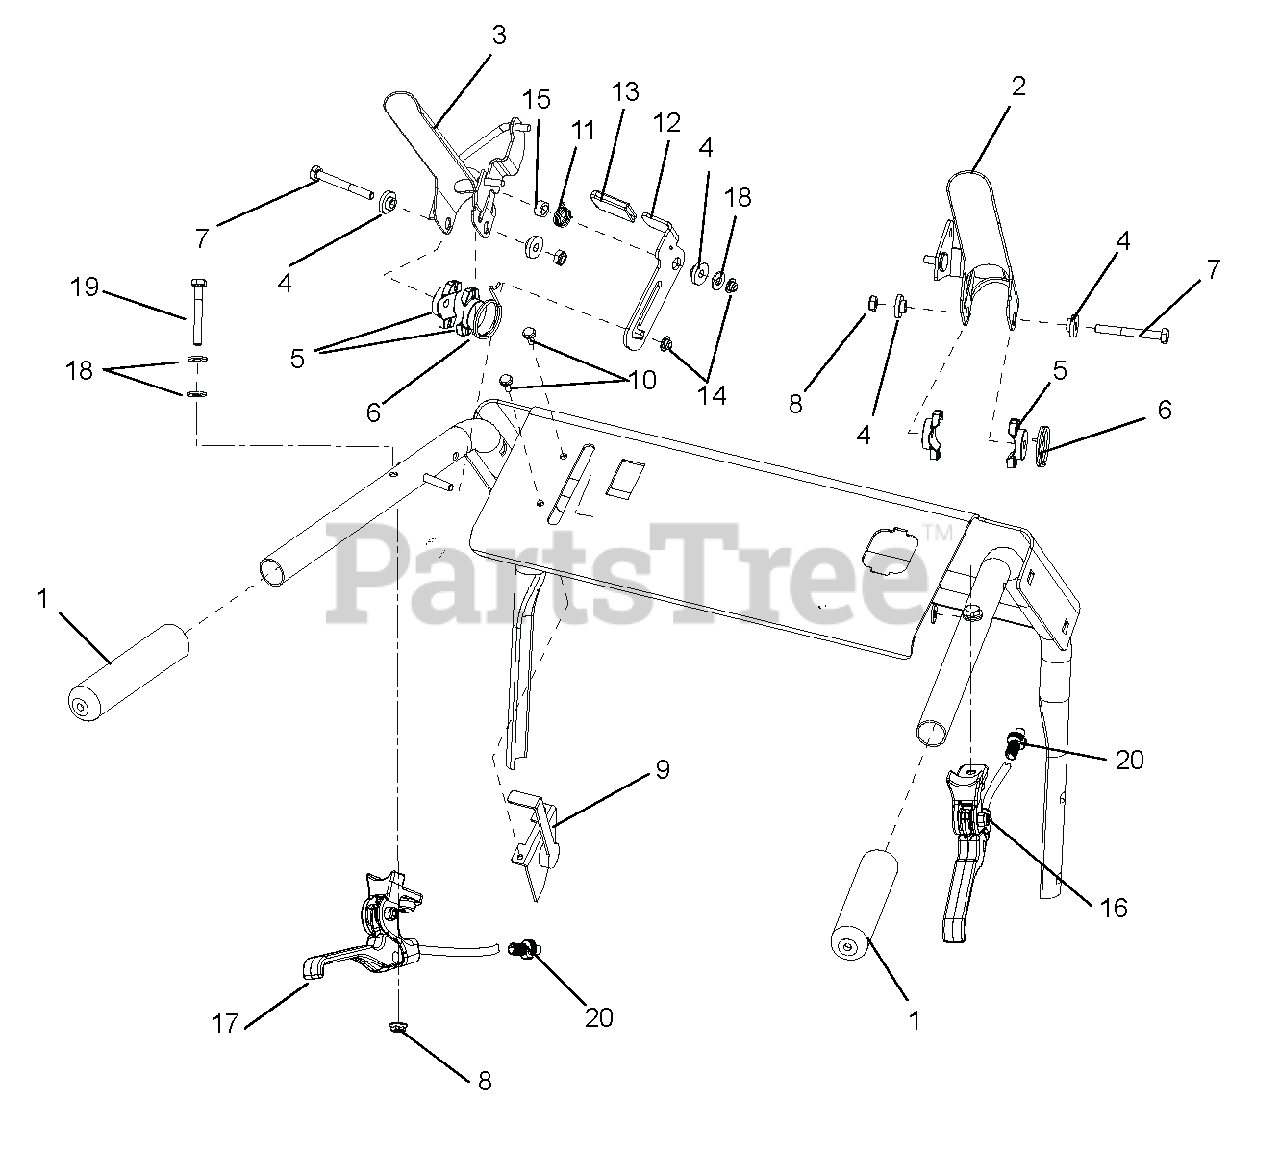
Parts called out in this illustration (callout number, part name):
1	HANDLE GRIP
2	PADDLE, P-BRAKE
3	HANDLEBAR, CE LH (WELDMENT)
4	BSHG, FLG .266X.42X.150 PM
5	SPACER, HANDLEBAR
6	SPRING, TORSION
7	@BLT-HEX .25-20X2.25 GR5 YWZC
8	NUT-JAM-NYL .250-20 W/INSERTYZ
9	CABLE, WAW THROTTLE
10	@SCR-TAP 10-24X.50 HWH TR YWZC
11	SG-TORS
12	BRKT-LEVER, INTERLOCK
13	GRIP, THUMB LATCH
14	PUSH NUT, .25
15	TUBE-SPACER .33X.50X.XX
16	CONTROL-LEVER W/CABLE FORWARD
17	CONTROL-LEVER W/CABLE REVERSE
18	@WSHR-FL-STL.281X.62X.065 YWZC
19	@BLT-HEX .25-20X2.00 GR5 YWZC
20	CABLE ADJUSTER, STEEL
